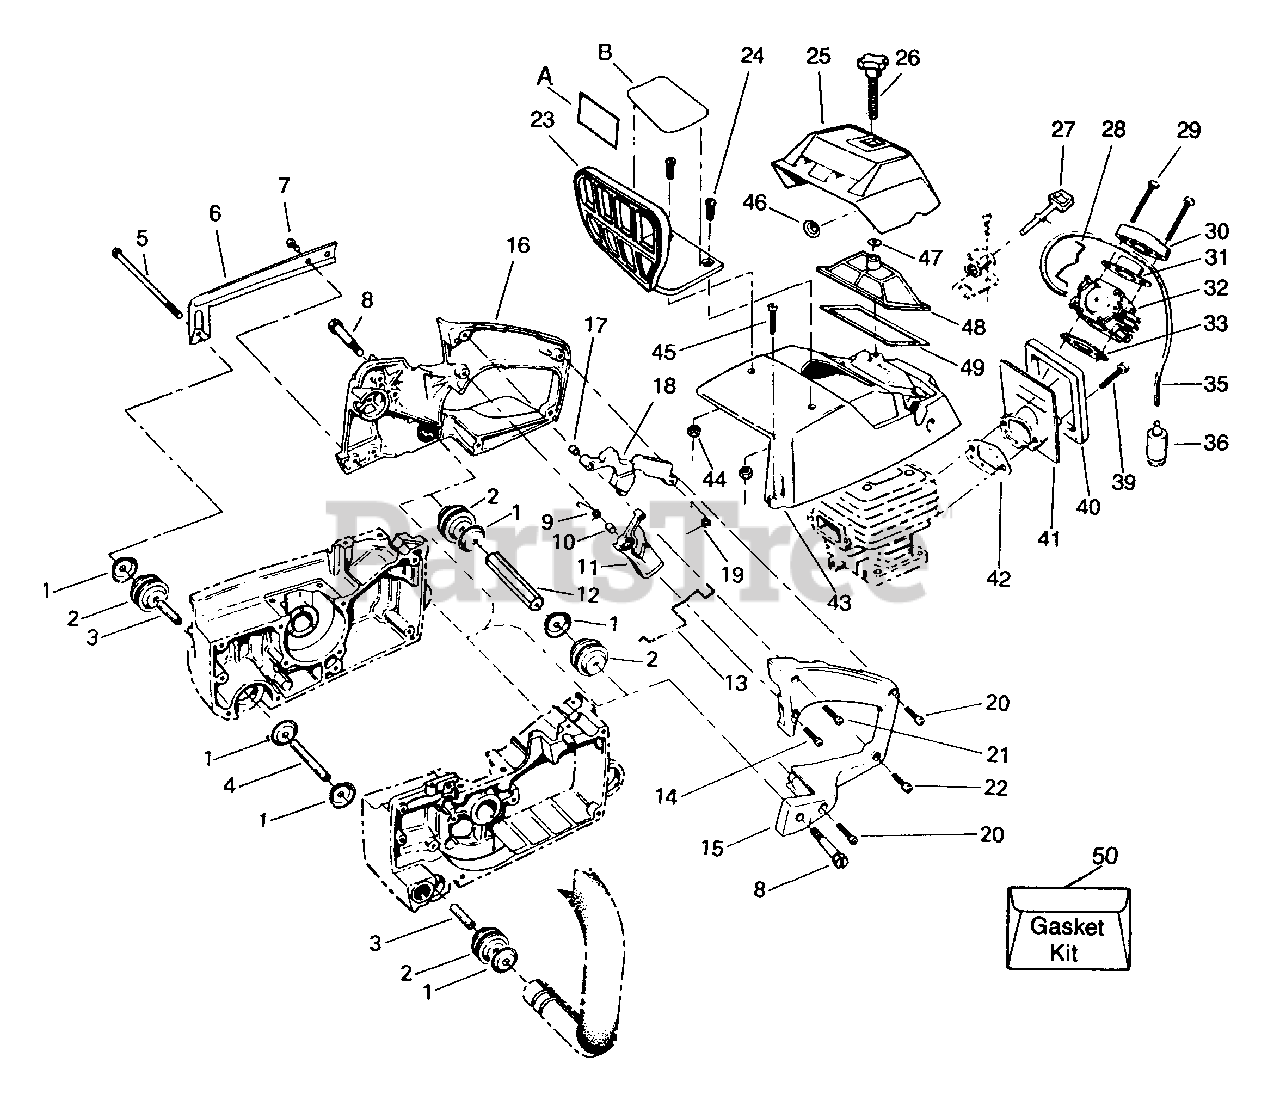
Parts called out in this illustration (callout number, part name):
1	Cup-Isolator
2	Isolator-Powerhead/Rear Handle
3	Spacer- Front Handlebar Isolator Mount.
4	Spacer - Front Handlebar Isolator Mount
5	Screw - 1/4-20 x 5-5M6
6	Handle Brace
7	Screw-1/4-20 x 3/4 Button Md.
8	Shoulder Screw-Isolator
9	Spring-Trigger
10	Bushing-Trigger
11	Throttle-Trigger
12	Spacer- Isolator (Center)
13	Throttle Link
14	Shoulder Screw - 10-24x5/8 - Fil. Md. - Throttle Trigger
15	Rear Handle Left
16	Rear Handle Right
17	Bushing- Throttle Lock
18	Throttle Lock
19	Spring- Throttle Lock
20	Screw - 10-24 x 13/16 Rear Handle
21	Screw-8-32 x 13/16 Fil. Hd. Rear Handle Throttle Lock
22	Screw-8-32 x 9/16-Fil. Hd. Rear Handle Lower
23	Handguard
24	Screw-10-24x1/2
25	Cover-Carburetor
27	Choke Rod
28	Wire-Choke
29	Screw -10-24 x 1-5/8 Fil. Hd. Carburetor to Adaptor
30	Seal - Adaptor Shield
31	Bracket- Carburetor Seal
32	Carburetor
33	Gasket- Carburetor to Adaptor
35	Line Kit
36	Fuel Pick-Up Ass'y
39	Screw-10-24x1-3/16 Hex Md. Adaptor to Cylinder
40	Seal- Carburetor Adaptor
41	Carburetor Adaptor
42	Gasket - Adaptor to Cylinder
43	Cylinder Shield
44	Nut-#10
45	Screw-10-24 x 5/8 Fit. Hd. Cylinder Shield to Crankcase
47	Retainer -Carb. Cover Knob
48	Air Filter
49	Gasket- Air Filter
50	Kit-Gasket
A	Decal-Kickback Guide Bar Powerhead
A	Decal-Kickback Bow Guide Powerhead
B	Decal- Starting Instructions
